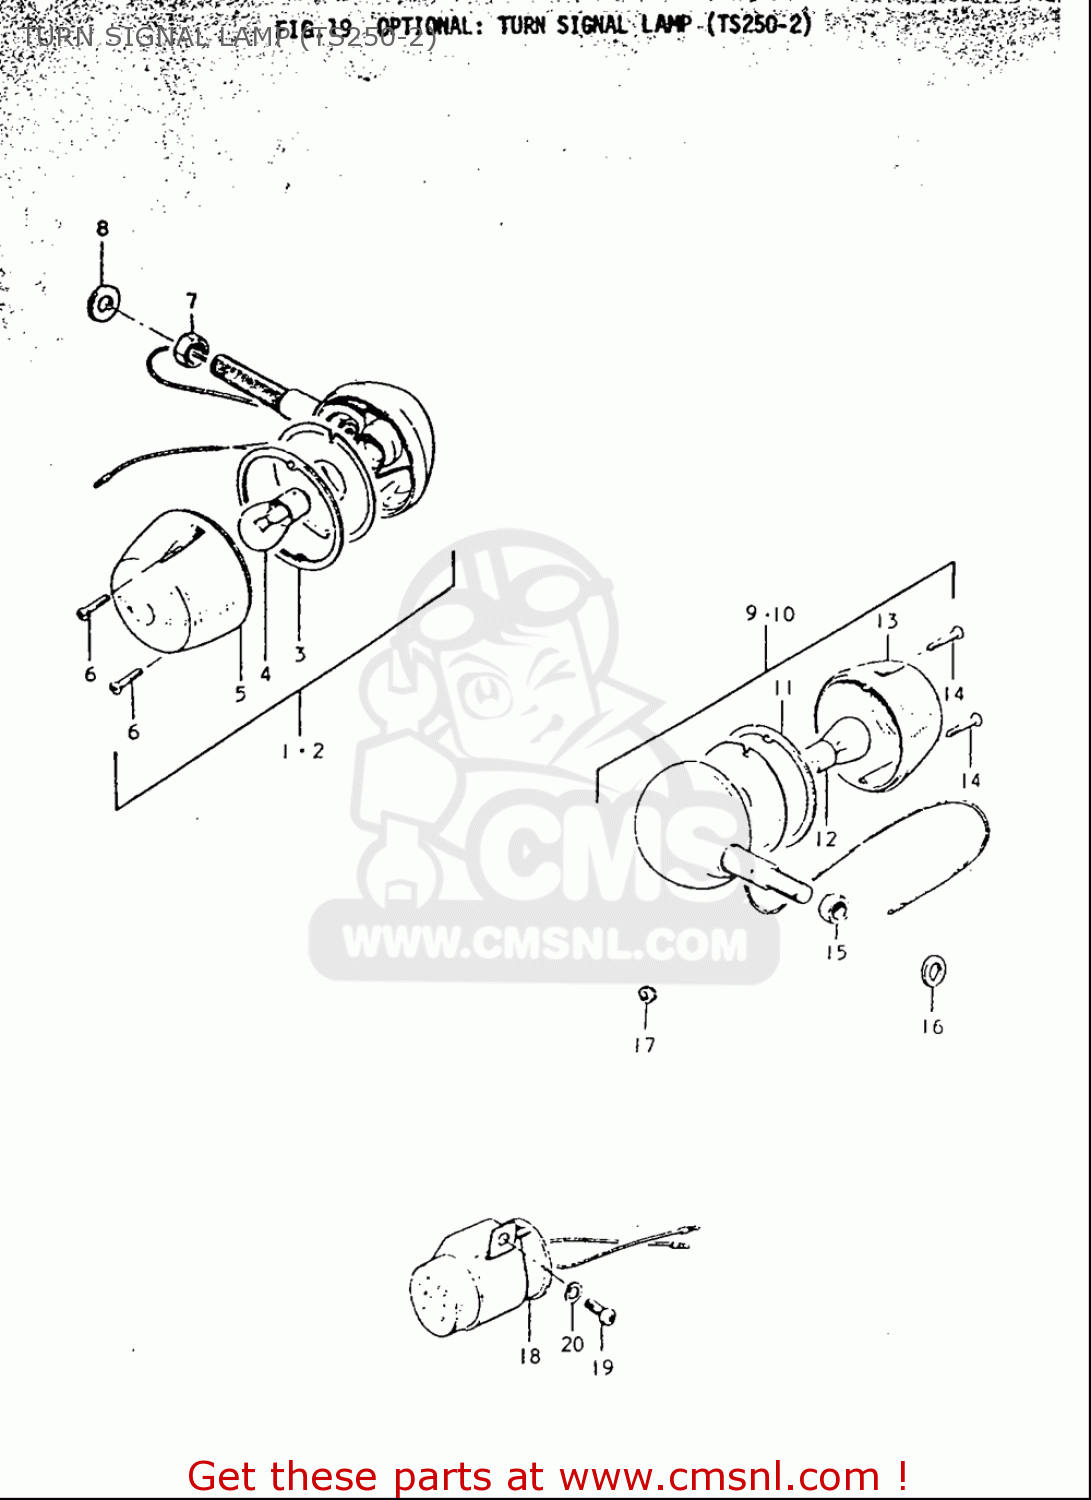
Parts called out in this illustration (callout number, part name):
3	GASKET,TURNSIGNAL LENS (NAS)
4	BULB(6V17W,STANLEY,A4513A)
5	LENS,TURNSIGNAL
6	SCREW
7	NUT
8	WASHER
11	GASKET,TURNSIGNAL LENS (NAS)
12	BULB(6V17W,STANLEY,A4513A)
13	LENS,RR TURNSIGNAL LAMP
14	SCREW
15	NUT
16	WASHER
19	SCREW
20	WASHER,LOCK
